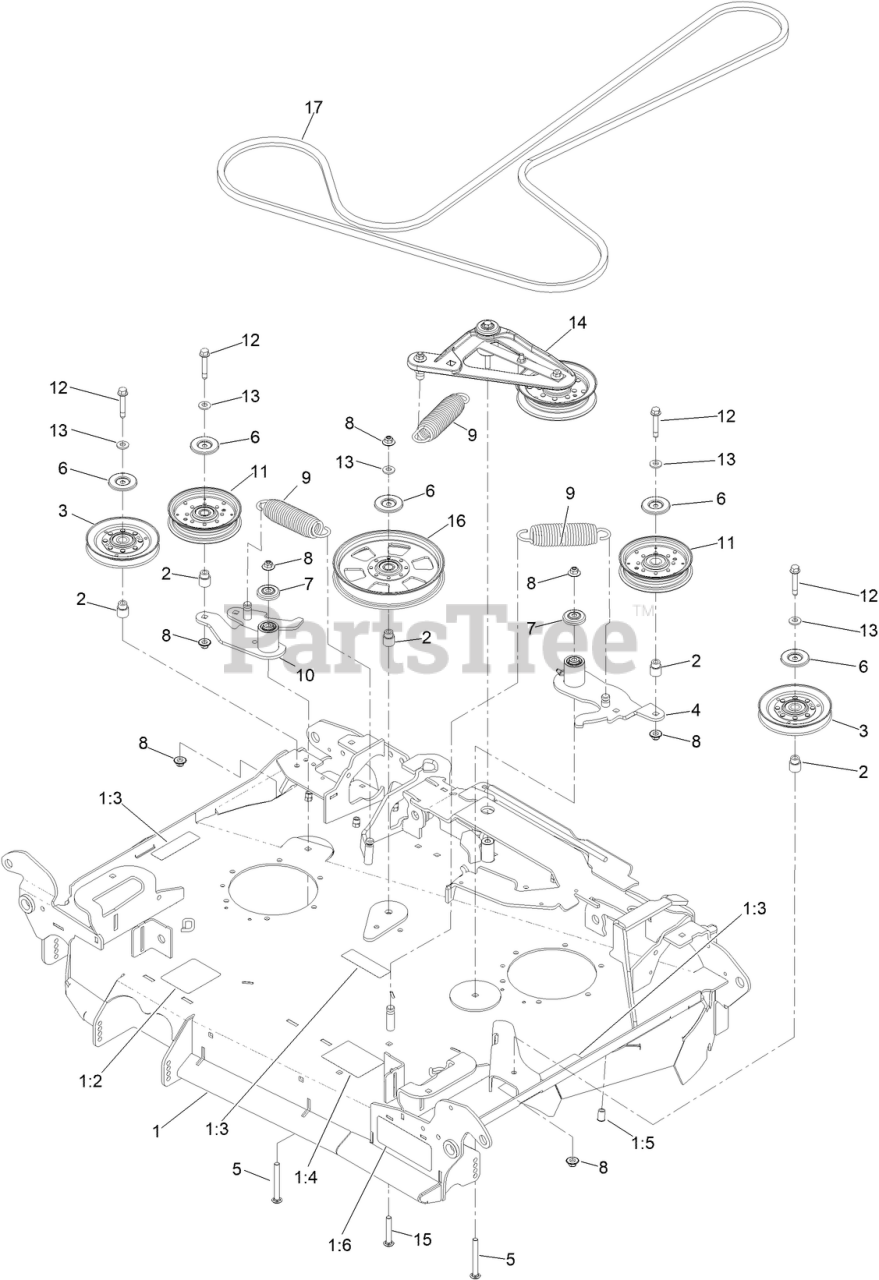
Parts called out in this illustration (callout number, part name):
1	ASM-DECK, CTR 96G [TORO]
1:2	DECAL-ROLLER, ANTI-SCALP
1:3	DECAL-COVER, MISSING
1:4	DECAL-BELT ROUTING
1:5	NUT-CLINCH,HEX
2	BUSHING-IDLER
3	IDLER-V
4	IDLER ASM
5	BOLT-SHOULDER, CARRIAGE
6	SHIELD-DUST
7	GUARD-TOP
8	NUT-FLANGE, NI
9	SPRING-EXTENSION
10	IDLER ASM
11	PULLEY-IDLER, FLAT
12	SCREW-HHF W/ PATCH
13	WASHER-BELLEVILLE
14	DECK IDLER ASM
15	SCREW-CARR
16	PULLEY-IDLER, FLAT
17	V-BELT
